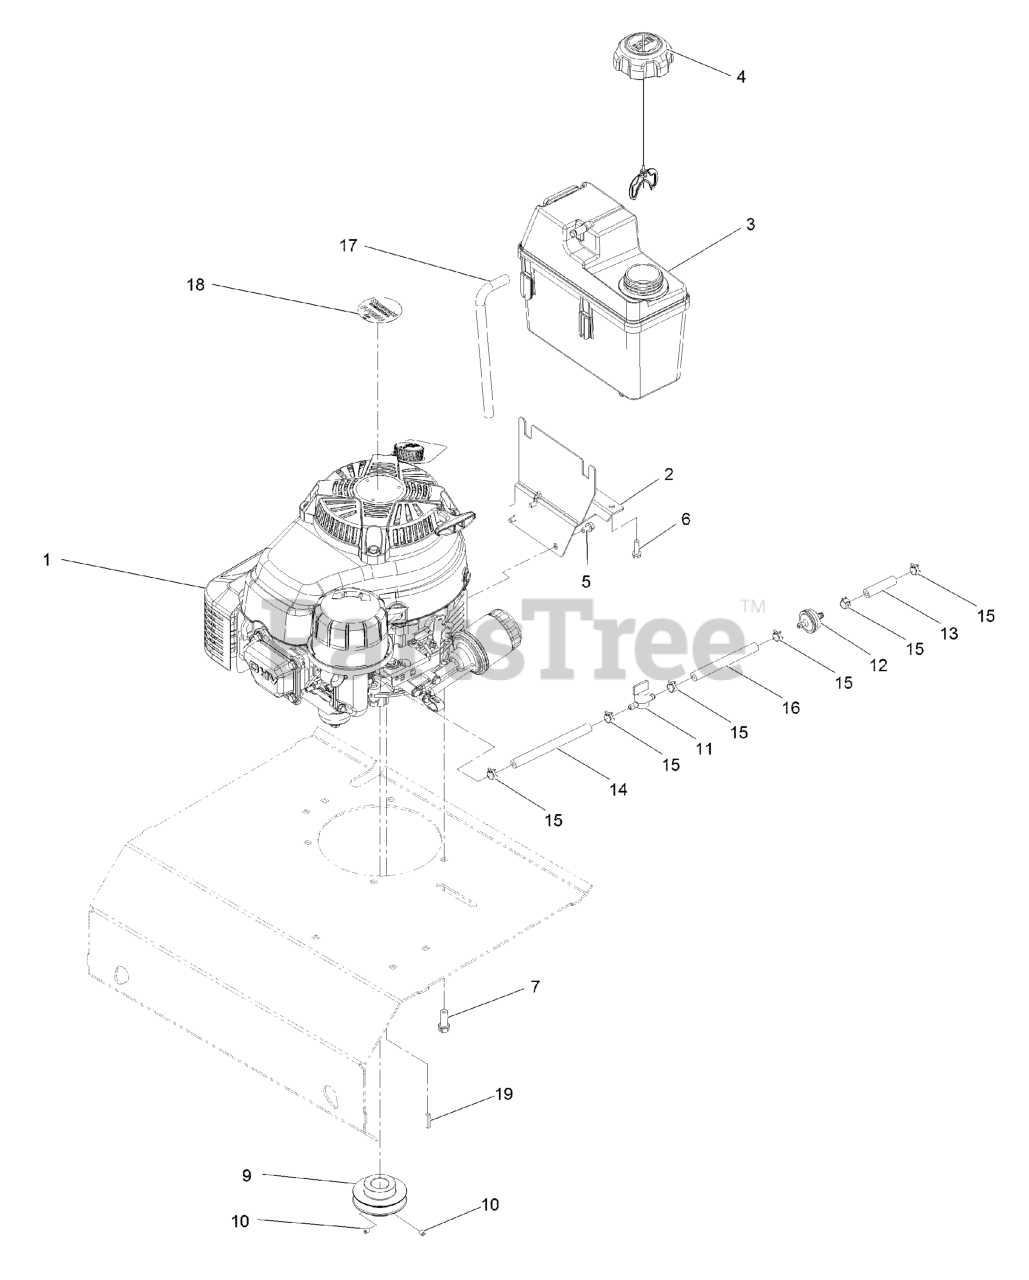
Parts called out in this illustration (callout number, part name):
2	MOUNT-TANK
3	TANK-FUEL
4	CAP-FUEL
5	SCREW-HWH
6	SCREW-HWH
7	SCREW-TAPTITE
9	PULLEY-DRIVER
10	SCREW-SET, HSH
11	VALVE-FUEL
12	Filter-Fuel
13	HOSE-FUEL
14	HOSE-FUEL
15	CLAMP-HOSE
16	HOSE-FUEL
17	HOSE-VENT, CANISTER
